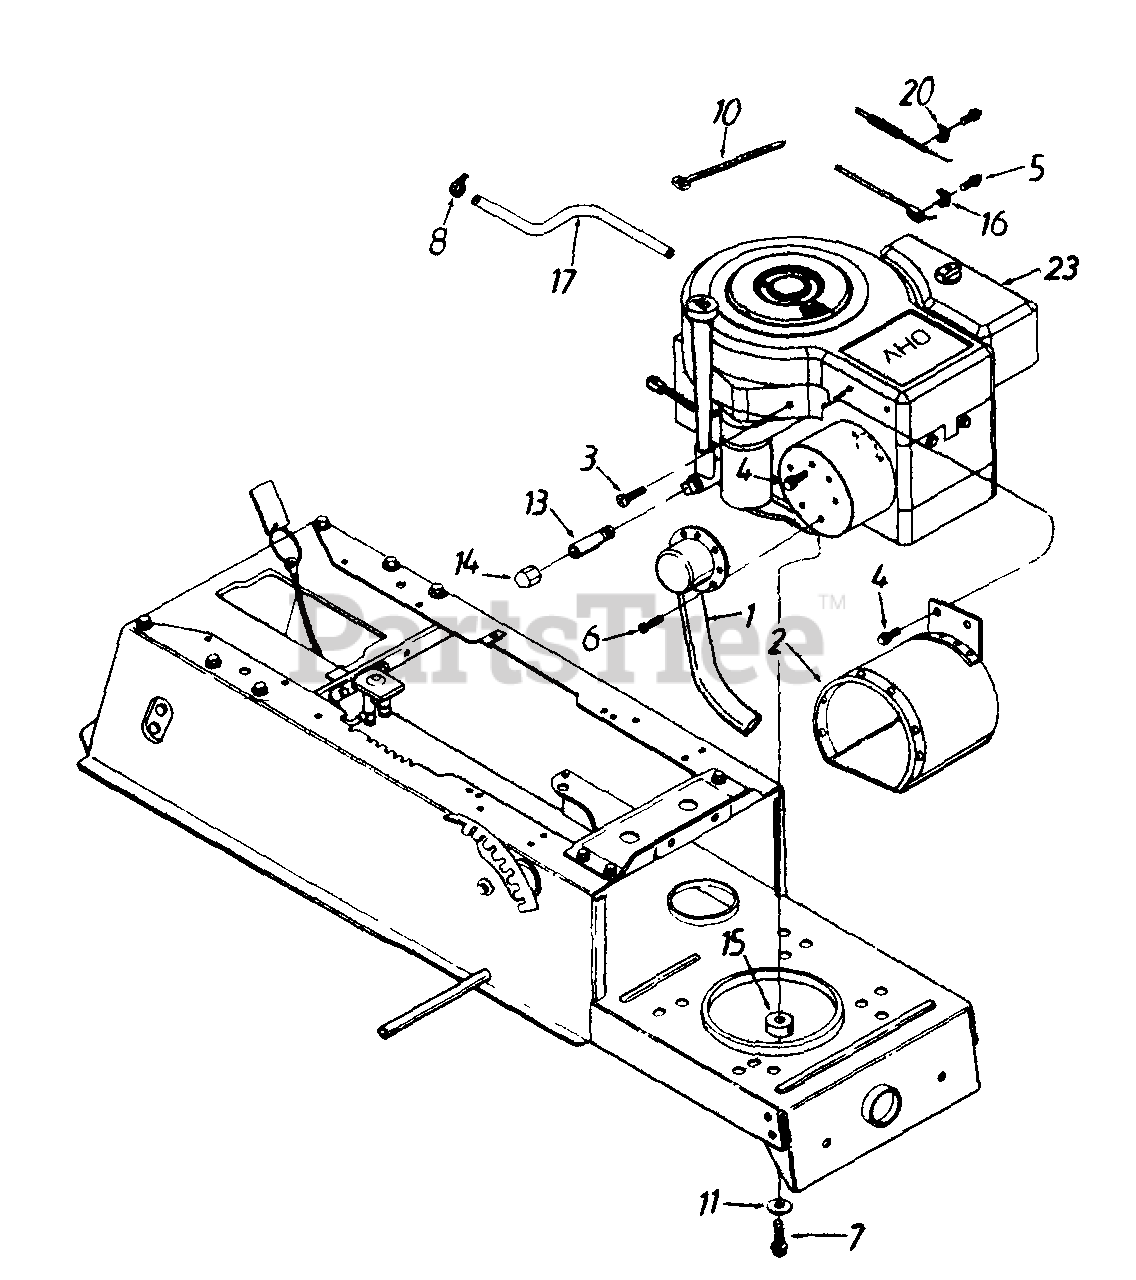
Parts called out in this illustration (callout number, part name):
1	Exhaust Pipe Ass'y.
2	Heat Shield Ass'y
3	Pan Hd. Mach. Scr 5/16-18 x .75"
4	Hex Wash. Hd. Scr. 1/4-20 x .5"
5	Hex Slot Wash. Hd. #10-32 x 5/8" Lg.
6	Hex Wash. Hd. F-Tap Scr. #8-32 x .38"
7	Hex L-Wash. TT-Tap Scr. 3/8-16 x 1.5"
8	Hose Clamp -.49" Dia.
10	Cable Tie - 4" I. D
11	Flat Wash. 3/8" I.D. x 1.25" O.D.
13	Pipe Nipple 3/8-18 NPT x 2" Lg.
14	Cap - Oil Drain
15	Shld. Spacer .38" I.D. x 1.25" O.D.
16	Casing Clamp
17	Fuel Line Hose
20	Casing Clamp
23	Engine
